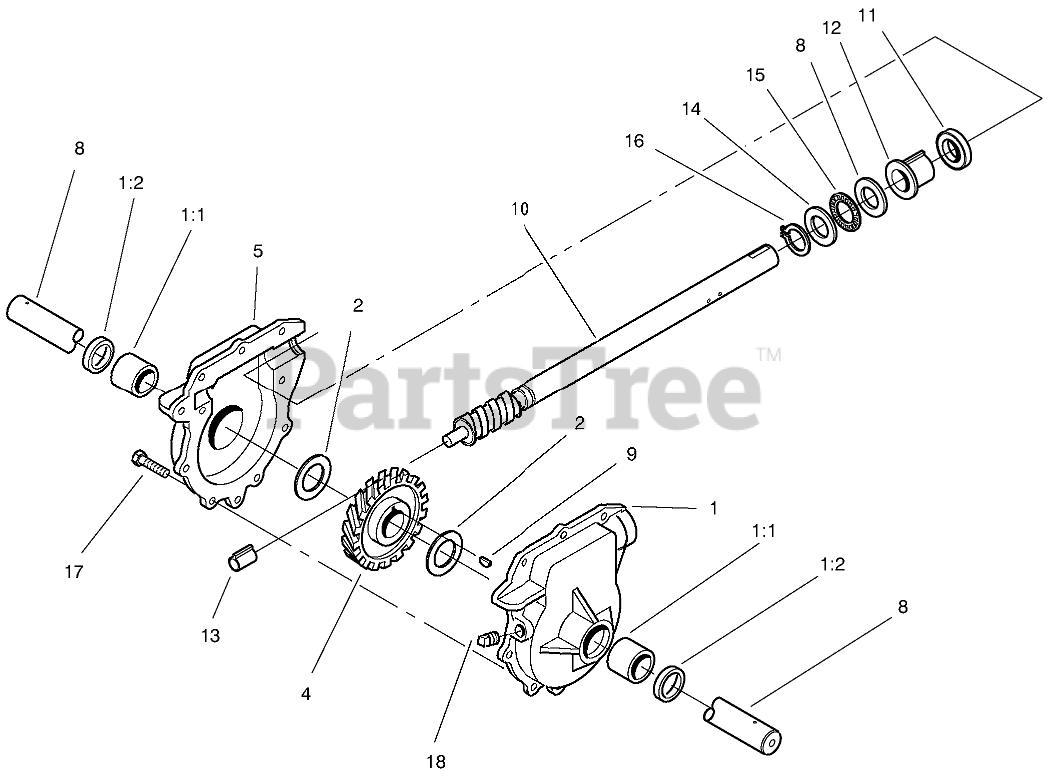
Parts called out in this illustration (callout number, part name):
1	ASM-Gearcase LH
1:1	BUSHING
1:2	SEAL-OIL
2	WASHER-THRUST
4	GEAR-HELICAL
5	Auger Gearcase
8	SHAFT-AUGER
9	KEY-WOODRUFF
10	SHAFT-IMPELLER
11	SEAL-OIL
12	BUSHING-INPUT
13	BUSHING-WORM
14	WASHER-THRUST
15	BEARING-THRUST
16	RING-RETAINING, Ext
17	SCREW-HWH
18	PLUG-PIPE, SQH
